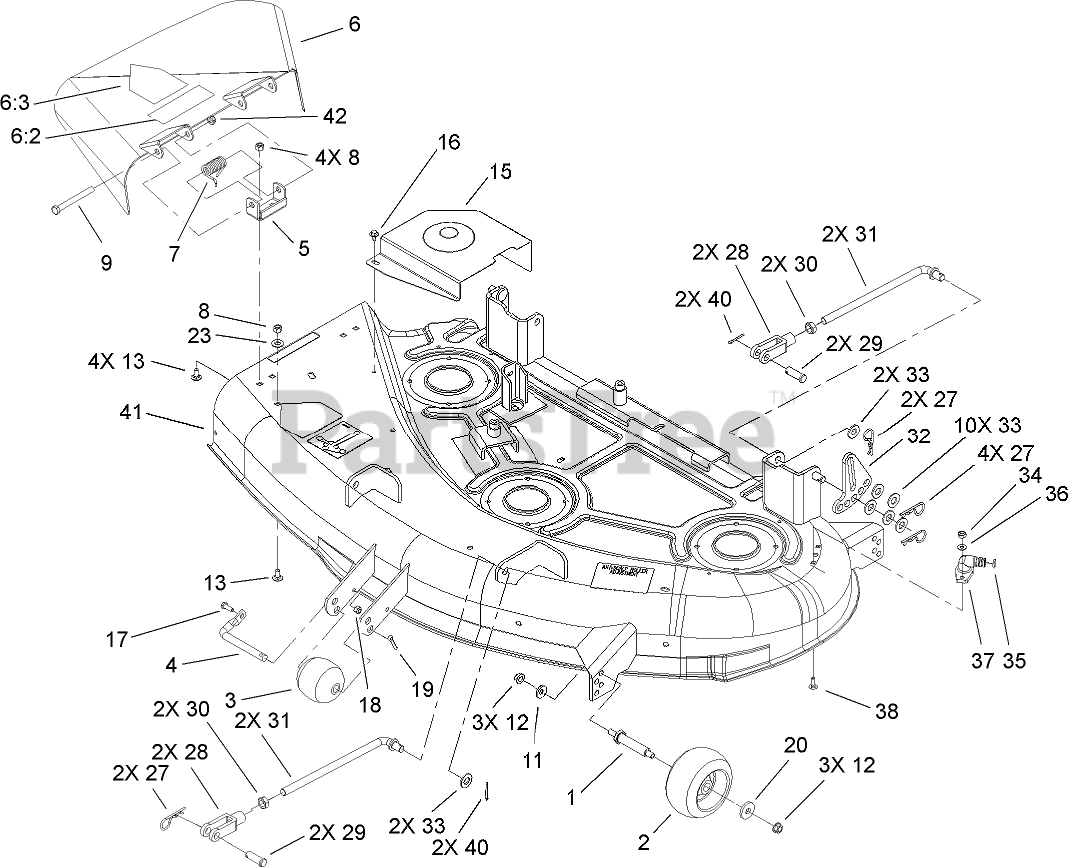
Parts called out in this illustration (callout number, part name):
1	SPACER
2	ROLLER-SCALP, ANTI
3	ROLLER
4	Shaft-Roller
5	BRACKET-PIVOT
6	DEFLECTOR ASM
6:2	DECAL-DANGER
6:3	DECAL-DANGER
7	SPRING
8	NUT-LOCK, NI
9	SCREW-HH
11	WASHER-BELLEVILLE
12	NUT-HHF, WHIZ
13	SCREW-CARR
15	COVER-BELT, RH
16	SCREW-HHFTF
17	SCREW-HH
18	NUT-LOCK, NI
19	PIN-COTTER
20	WASHER
23	WASHER-FLAT
27	PIN-COTTER
28	CLEVIS
29	PIN-CLEVIS
30	NUT-JAM
31	ROD-TRUNION
32	LINK-HOC, ADJUSTING
33	WASHER-FLAT
34	NUT-LOCK, NI
35	O-RING
36	WASHER-FLAT
37	FITTING-WASHOUT
38	BOLT-CARR
40	PIN-COTTER
41	44 INCH DECK ASM
42	NUT-HEX
